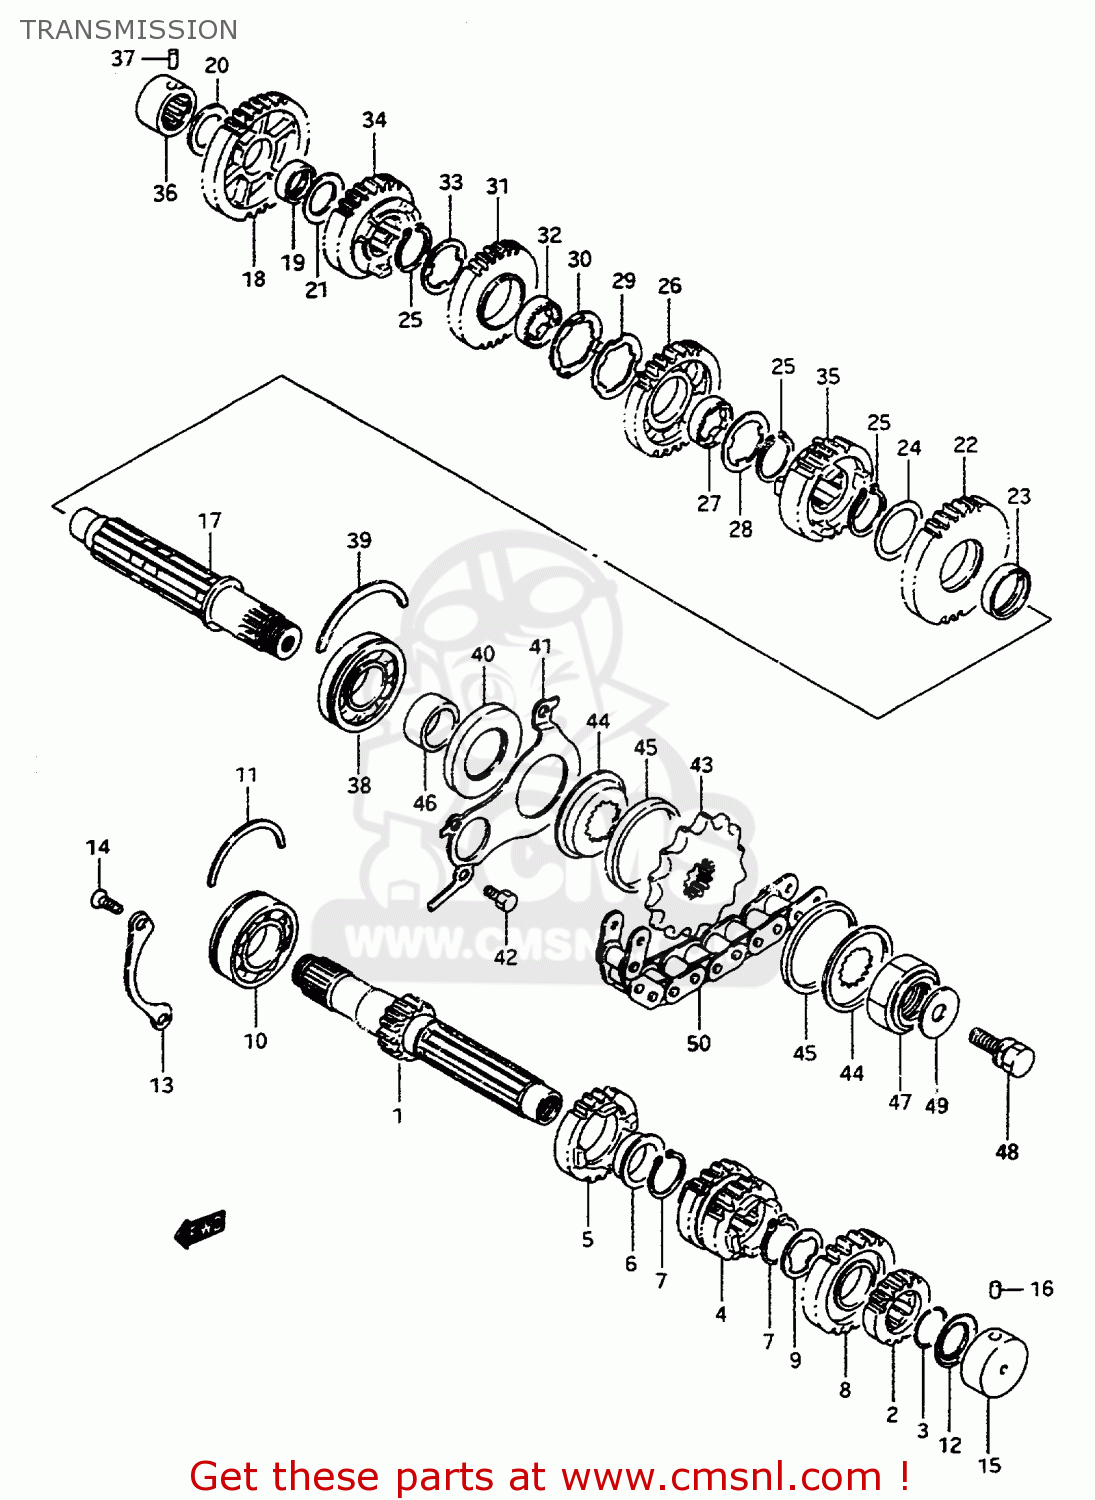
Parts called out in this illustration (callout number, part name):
1	SHAFT,COUNTER(NT:12)
2	GEAR,2ND DRIVE(NT:16)
3	CIRCLIP
4	GEAR,3RD & 4TH DRIVE(NT:17/20)
5	GEAR,5TH DRIVE(NT:22)
6	BUSHING
7	RING,SNAP
8	GEAR,SIXTH DRIVE (NT:21)
9	WASHER,LOCK
10	BEARING(25X62X17)
11	C RING
12	SEAL,OIL(20X31.2X2.7)
13	RETAINER,CNTR SHAFT BEARING
14	SCREW ,6X16
15	BEARING(20X34X17.5)
16	PIN
17	SHAFT,DRIVE
18	GEAR,1ST DRIVEN(NT:37)
19	BUSH(22X26X9)
20	SHIM(20X34X1)
21	SHIM(22X34X1)
22	GEAR,2ND DRIVEN(NT:33)
23	BUSH(28X32X9.5)
24	SHIM(28X38X1)
25	CIRCLIP
26	GEAR,3RD DRIVEN(NT:28)
27	BUSH
28	WASHER,LOCK
29	WASHER,LOCK
30	WASHER
31	GEAR,4TH DRIVEN(NT:28)
32	BUSH
33	WASHER,LOCK
34	GEAR,5TH DRIVEN(NT:27)
35	GEAR,SIXTH DRIVEN (NT:23)
36	BEARING(20X34X20)
37	PIN
38	BEARING(25X62X17)
39	C RING
40	SEAL,OIL(34X62X6)
41	RETAINER,DRIVE SHAFT OIL SEAL
42	BOLT
43	SPROCKET,ENGINE
44	HOLDER,SPROCKET DAMPER
45	DAMPER,SPROCKET
46	SPACER(25X34X16.1)
47	NUT
48	BOLT
49	WASHER
50	CHAIN,DRIVE(112LE)
